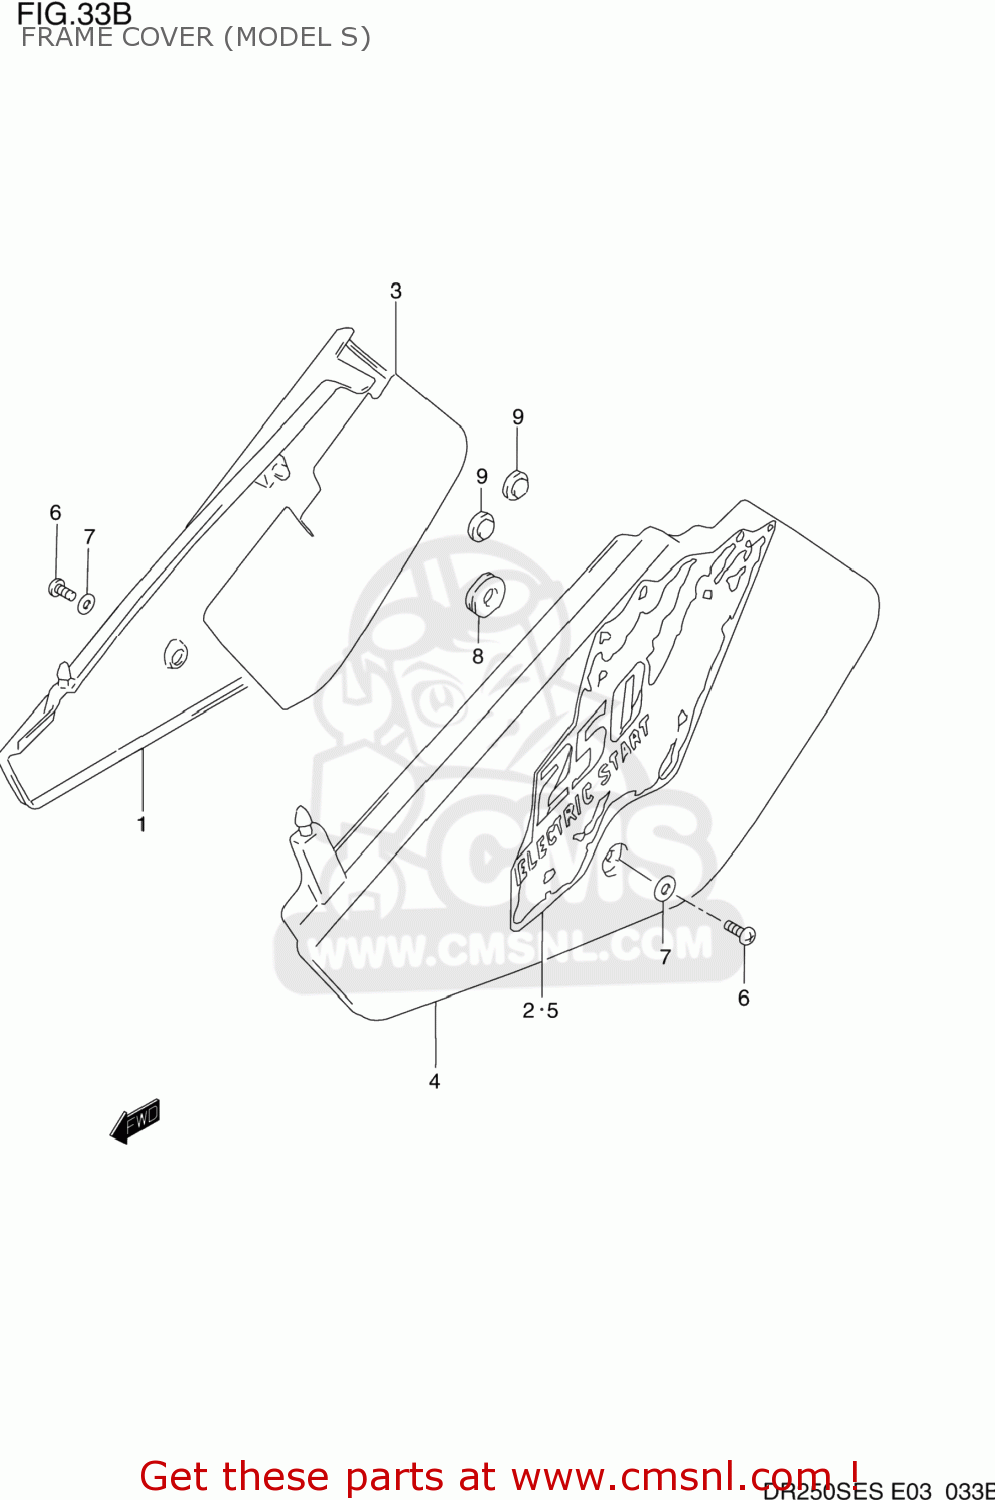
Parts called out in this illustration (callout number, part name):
1	COVER,FRAME,R(WHITE)
2	TAPE,FRAME COVER,RIGHT
3	SHIELD,FRAME COVER,R
4	COVER,FRAME,L(WHITE)
5	TAPE,FRAME COVER,LEFT
6	SCREW
7	WASHER
8	CUSHION
9	CUSHION
